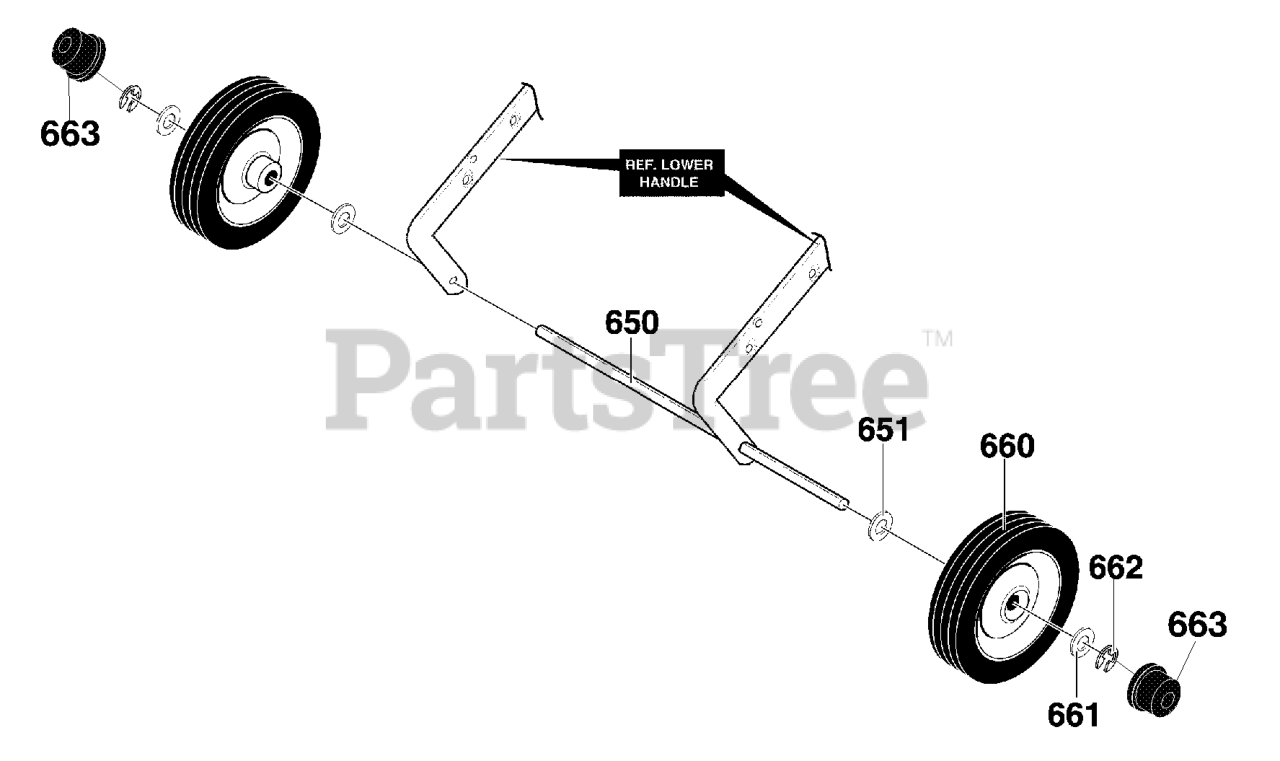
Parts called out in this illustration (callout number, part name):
650	AXLE SHAFT
651	WASHER, FLAT .391X1.00X1.25
660	TIRE & RIM
661	WASHER, FLAT .391X1.00X.125
662	RING, RET E
663	HUB CAP
